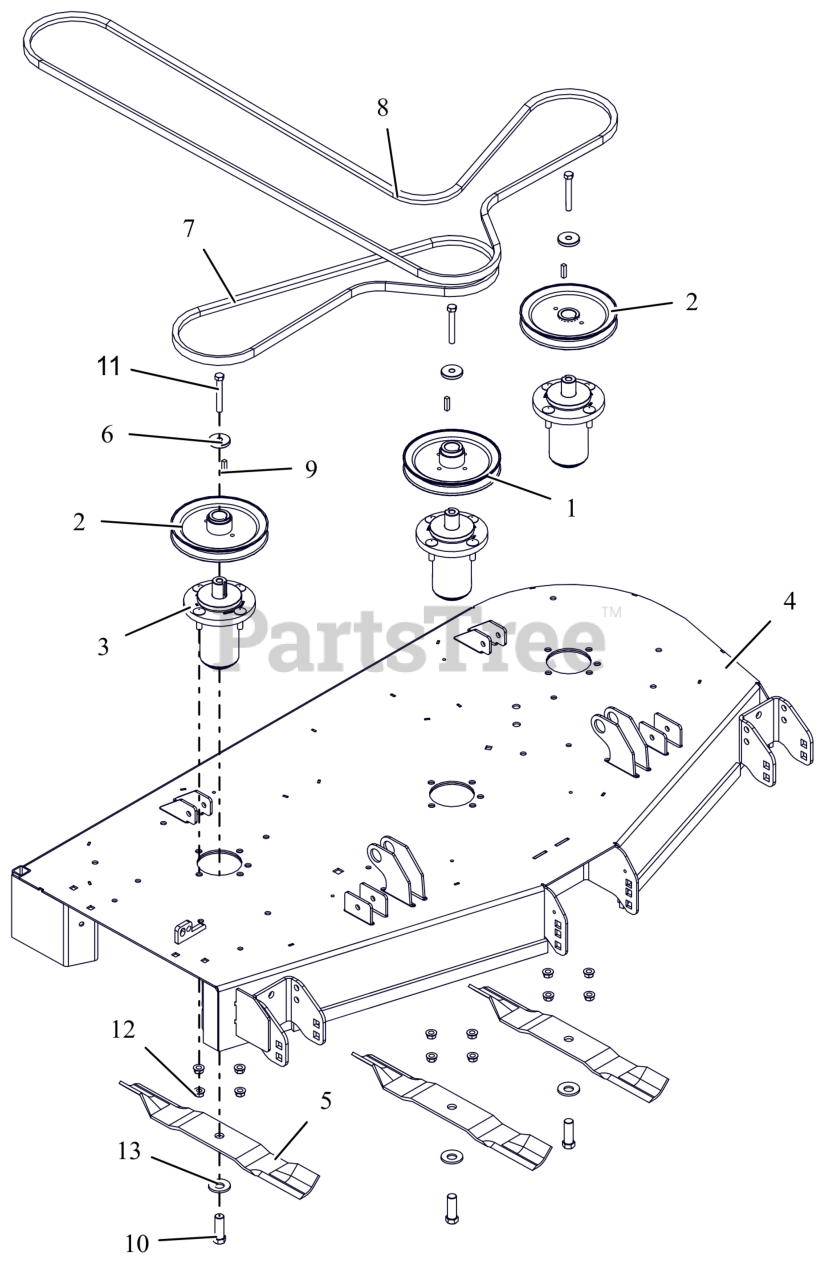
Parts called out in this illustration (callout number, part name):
1	PULLEY, DOUBLE-1"ID X 6.75"OD
2	PULLEY, V-1" ID X 6.75" OD
3	ASM, MAINT FREE ALUM SPINDLE
4	KIT,DECK-52" W/DECALS-ARIENSCE
5	BLADE, 18"
6	RETAINER, SHEAVE
7	V-BELT, B-COGGED
8	V-BELT, HB SECTION
9	KEY, SQ .25X.25X1.00 RC 40-50
10	BLT, HEX .62-18X1.75 G8 ZCC
11	BLT, HEX .38-16X2.75 G8 ZCC
12	NUT-LK-CTR-FLG .375-16 GF ZCC
13	WSHR-BLVL .669X1.535X.138
